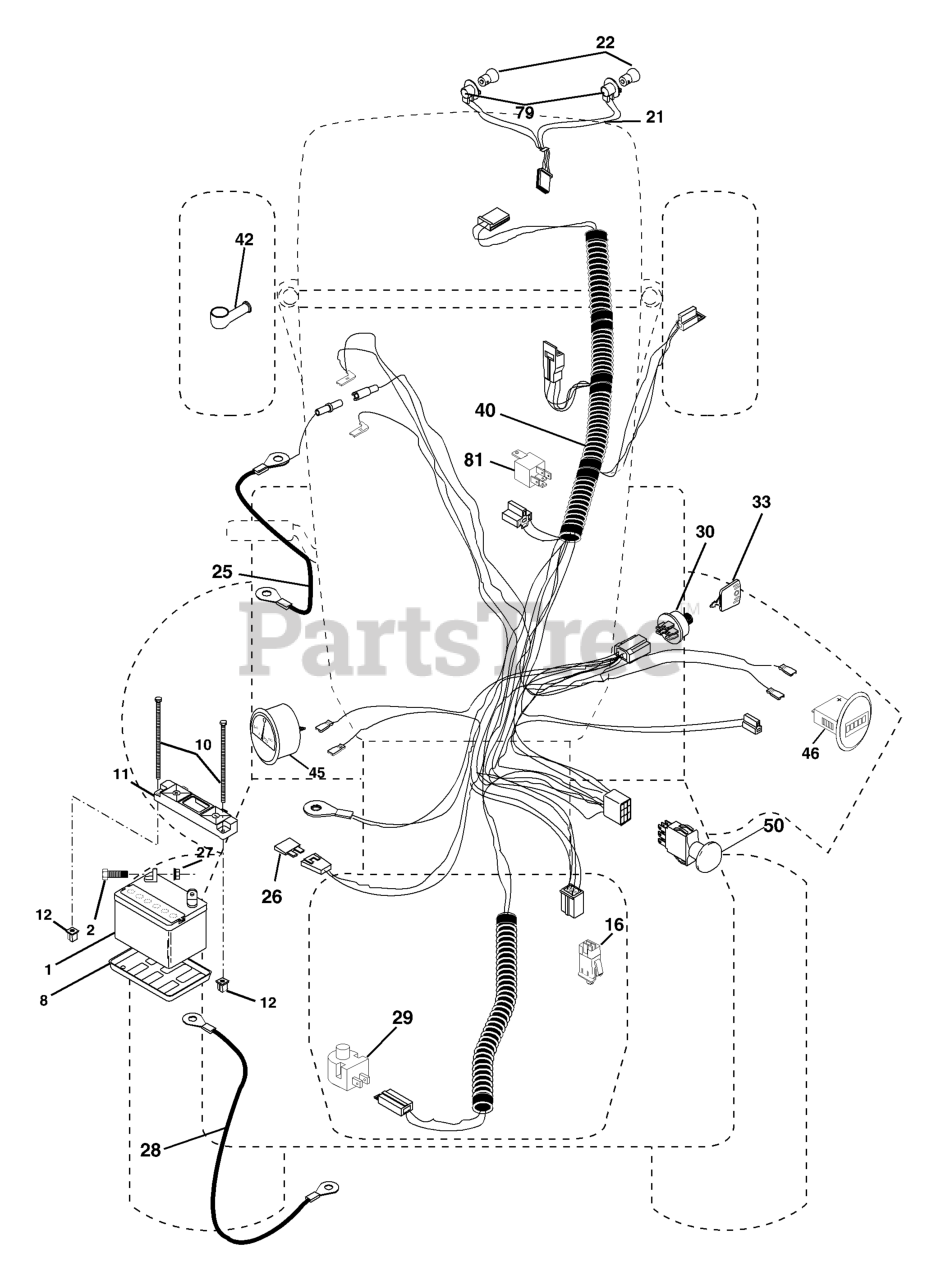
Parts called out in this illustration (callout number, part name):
1	BATTERY 12V .35 AMP
2	BOLT.HEX.1/4.X.3/4.DICHROMATE
8	BATTERY TRAY T
10	BOLT 1/4-20 X 7.5
11	BATTERY HOLDDOWN FRONT MOUNT
12	NUT, PUSH NYLON 1/4" BATTERY
16	SWITCH INTERLOOK PUSH-IN
21	HARNESS.W/LIGHT SOCKET
25	CABLE.4GA.RED.W/16GA.RED.WIRE
27	NUT
28	CABLE, GROUND
29	RP.SWITCH.PLUNGER.NC.GRAY
30	IGNITION SWITCH
33	KEY MLD GEN DELTA
40	HARNESS.IGNITION.VGT.NO.RELAY
42	COVER.TERMINAL.RED
45	RP AMMETER.ROUND.SILVER.DELTA
46	RP HOURMETER SNAP-IN
50	RP.PTO.SWITCH.8 TERMINAL.BLACK
79	BULB HOLDER ASM.
81	RELAY.ASSY.T
